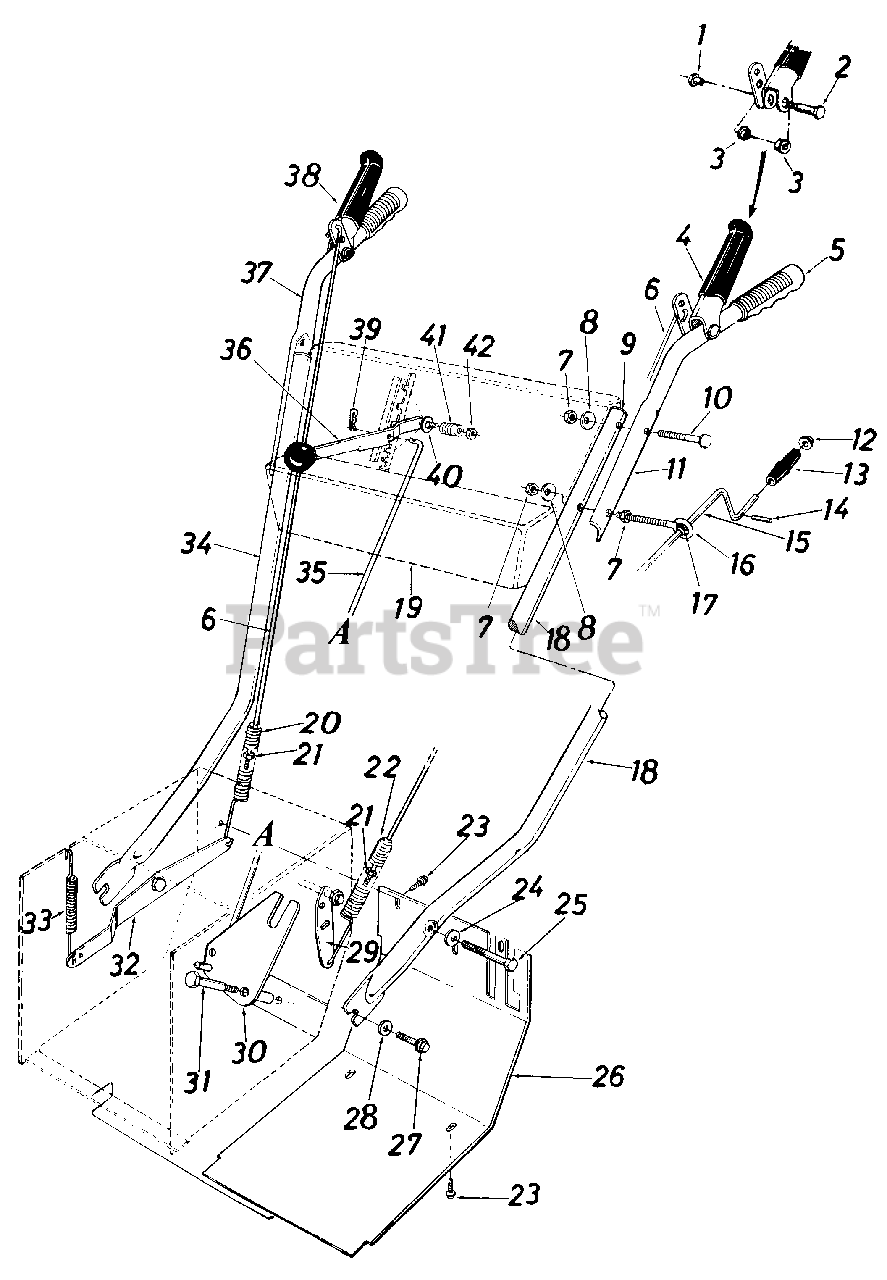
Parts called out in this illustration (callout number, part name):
1	Shld. Nut 1/4-20 Thd.
2	Shld. Bolt .374 Dia. x 1.53"-Lg.
3	Hex Flange Plastic Bearing .38" I.D.
4	Clutch Grip Ass'y.-L.H.
5	Grip
7	Hex Nut 5/16-18 Thd.*
8	Bell-Wash. .34" I.D. x .88" O.D.
9	Plastic Plug
10	Curved Carriage Bolt 5/16-18 x 2.0" Lg.
11	Upper Handle-L.H.
12	Push Nut 3/8" Rod
13	Knob 3/8" Rod
14	Roll Pin .12 Dia. x .631" Lg.
15	Chute Crank Ass'y.
16	Eye Bolt 5/16-18 x 5.0" Lg.
17	Plastic Bushing
18	Lower Handle-L.H.
19	Handle Panel Ass'y.
20	Extension Spring .75" O.D. x 5.0" Lg.
21	Hex Ins. L-Nut 1/4-20 Thd.
22	Extension Spring .75" O.D. x5.0" Lg.
23	Hex Wash. Hd. Self-Tap Scr. 5/16-24 x .50" Lg.
24	Bell-Wash. .40" I.D. x .88" O.D.
25	Hex Bolt 3/8-16 x 2.0" Lg.
26	Frame Cover
27	Pilot Hex Scr. 3/8-16 x .88"-Lg.
28	Bell-Wash. .40" I.D. x .88" O.D.
29	Drive Clutch Brkt. Ass'y.
32	Auger Clutch Brkt.
33	Extension Spring .38" O.D. x 3.18" Lg.
34	Lower Handle-R.H.
35	Shifting Rod
36	Shift Handle Ass'y.
37	Upper Handle-R.H.
38	Clutch Grip Ass'y.-R.H.
39	Int. Cotter Pin 5/16" Dia.
40	Bell-Wash. .40" I.D. x .88" O.D.
41	Compression Spring
42	Hex Ins. L-Nut 3/8-24 Thd.
